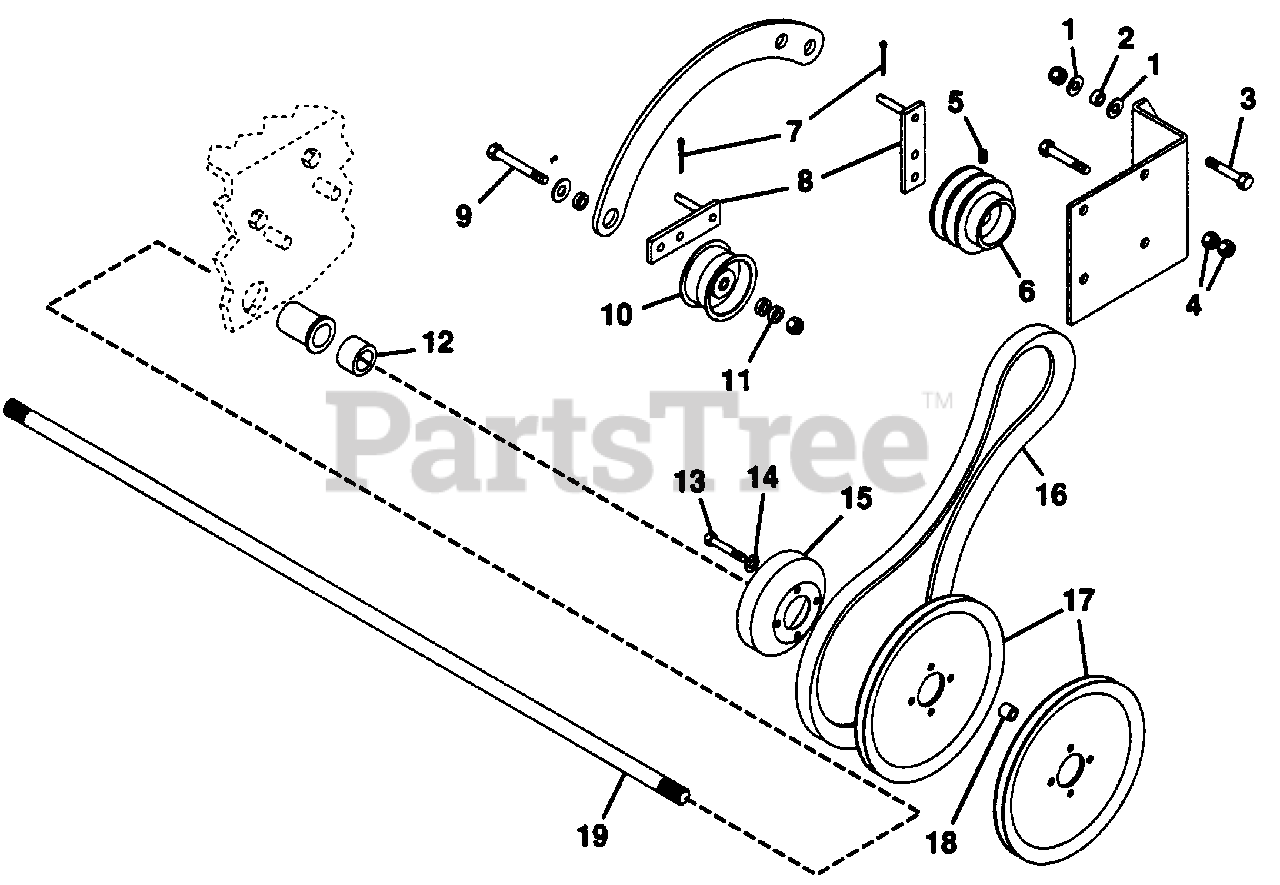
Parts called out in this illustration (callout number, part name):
1	Washer, Flat .406x.812x.065
2	Bushing, .391x.622x.670
3	Bolt, Hex 3/8-16x2.00
4	Nut, Lock 3/8-16
5	Screw, Set 5/16-18x.25 HSCK
6	Pulley, Jack-Shaft
7	Pin, Cotter .125x.75
8	Weldment, Idler Arm
9	Bolt, Hex 3/8-16x3.00
10	Sheave, Idler
11	Spacer, Idler .406x.750x.188
12	Spacer, Wheel
13	Bolt, Hex 5/16-18x1.50
14	Washer, Lock 5/16 Reg.
15	Drum, Brake
16	Belt, Set Traction
17	Pulley, Pro Wheel Drive
18	Spacer, Wheel Pulley
19	Shaft, Axle
